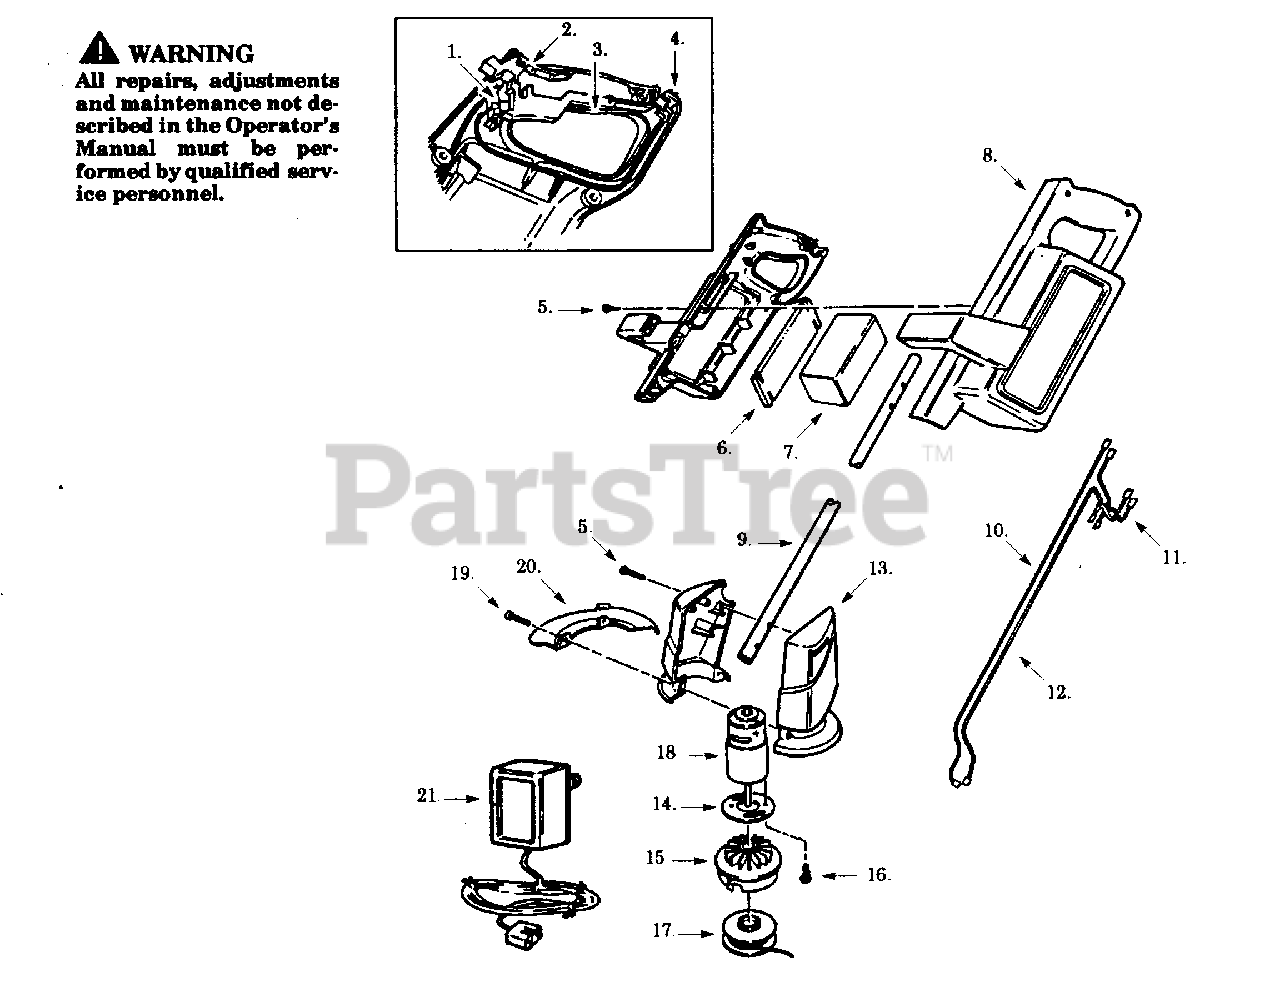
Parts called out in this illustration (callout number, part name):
2	Release Button
4	Receptacle Ass'y.
6	Foam Pad
8	Upper Hsg. Set
9	Handle Tube
10	Lead Wire (Red)
11	Lead Wire (Black)
12	Lead Wire (White)
13	Motor Hsg. Set
14	Motor Adapter
15	Rotating Head
17	Spool & Line
20	Foot Guard
21	Battery Charger
